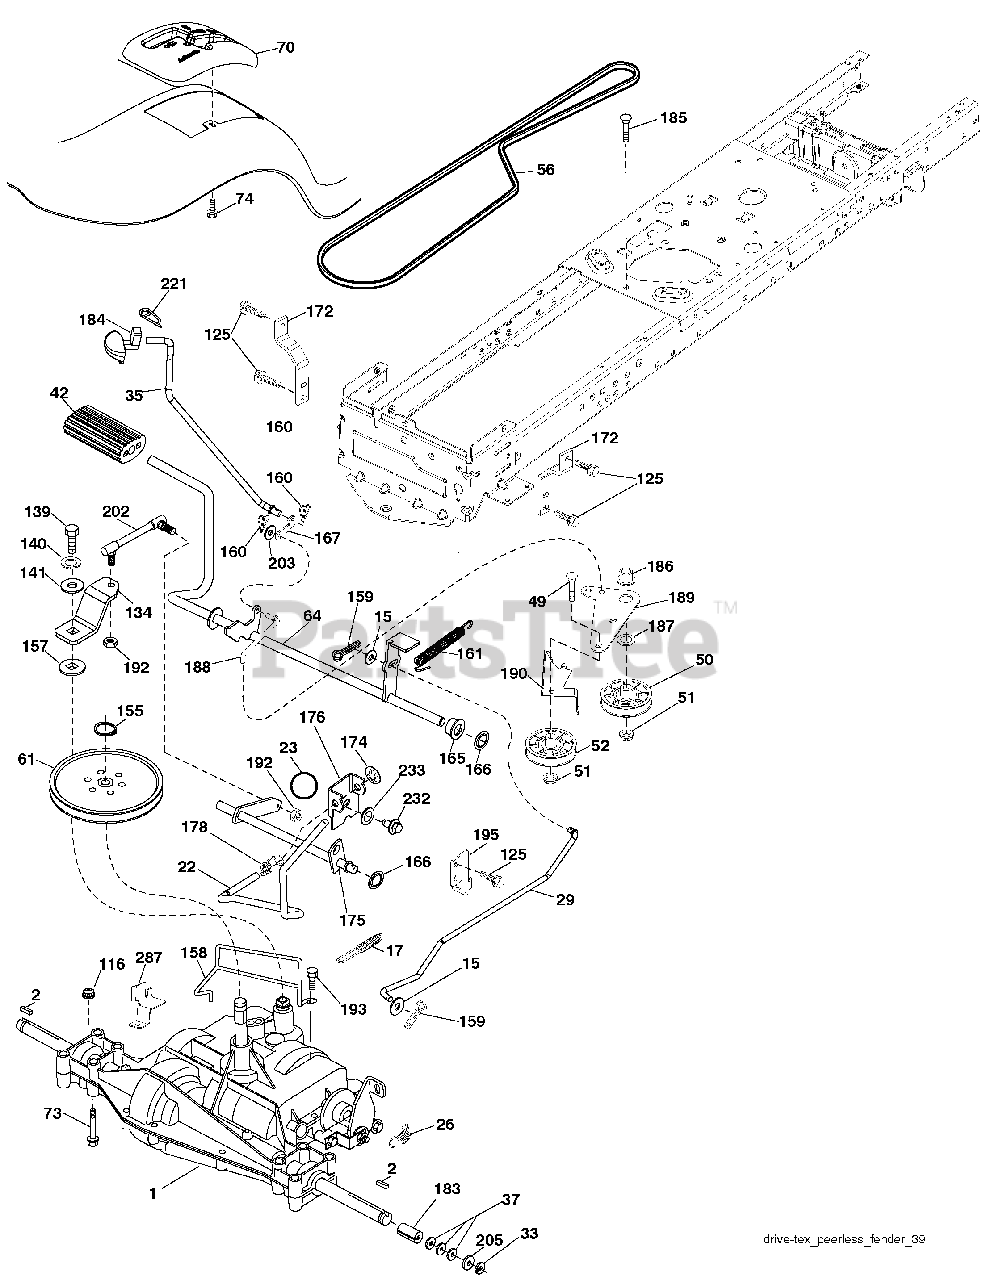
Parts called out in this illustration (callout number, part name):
2	Key Square
15	Washer 13/32 x 13/16 x 16 Ga.
17	Spring, Brake
22	Rod Shift
23	Knob
26	Spring Brake RTN
29	Rod, Brake
33	Ring E
35	Rod, Brake, Park
37	Washer 25/32 x 1-1/4 x 16 Ga.
42	Cover, Foot Pedal
49	Bolt
50	Pulley Idler Flat
51	Lock Nut 3/8-16
52	Idler V-Groove
56	V-Belt, Drive
61	Pulley Transaxle
64	Shaft Asm. Pedal Brake Control
73	Bolt 5/16-18 Gr. 5
74	Screw 1/4 x 1/2
116	Nut Lock Hex Flange 5/16-18
125	Screw 5/16-18 x 3/4
134	Arm Shift
139	Bolt 1/4-20 unf Gr. 8 w/Patch
140	Washer Lock Hvy Helical 1/4
141	Washer 9/32 x 3/4 x 10 Ga.
155	Ring Retainer
157	Washer Plate Shf
158	Keeper T/A
159	Pin Cotter 1/8 x 3/4
160	Retainer Clip
161	Spring, Return, Clutch
165	Busing Shaft Brake Hand Control
166	Nut Push .625
167	Latch Brake Parking
172	Strap Torque LH
174	Nut Push
175	Shaft Asm Shift
176	Arm Clevis Rod Shift
178	Spring Shift
183	Spacer, Axle
184	Handle Parking Brake
185	Bolt
186	Spacer Retainer
187	Washer
188	Link Clutch Ground Drive
189	Bellcrank Ground Drive
190	Keeper Bellcrank Ground Drive
192	Nut Lock Center 1/4-28
193	Screw 5/16-18 x 3/4
195	Bracket Brake Rod
202	Link Shift
203	Washer 11/32 x 11/16 x 16 Ga.
205	Washer 25/32 x 1-5/8 x 16 Ga.
221	Retainer Spring Clip Handle
232	Bolt 7/16-14 x 1 Gr. 5
233	Washer Serrated
287	Keeper Pulley T/A
